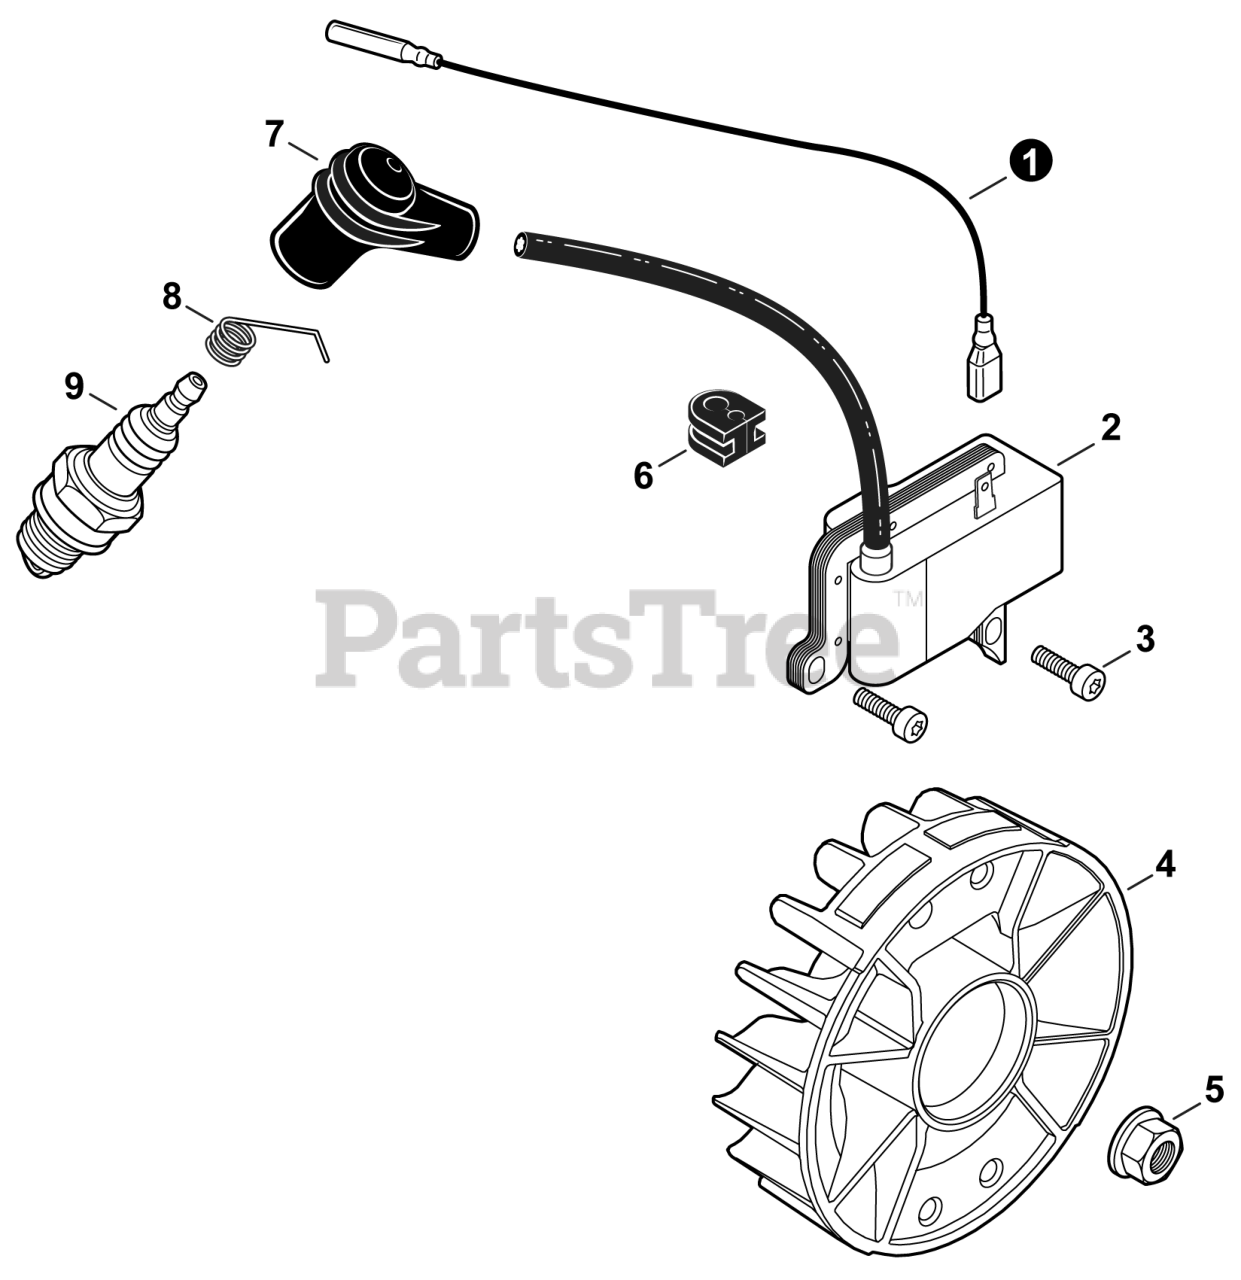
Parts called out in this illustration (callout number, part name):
1	LEAD L= 470
2	COIL, IGNITION
3	BOLT, TORX 5×20
4	FLYWHEEL
5	NUT, FLANGE 10×1.25
7	CAP, SPARK PLUG
8	TERMINAL, SPARK PLUG
9	SPARK PLUG - BPMR8Y
